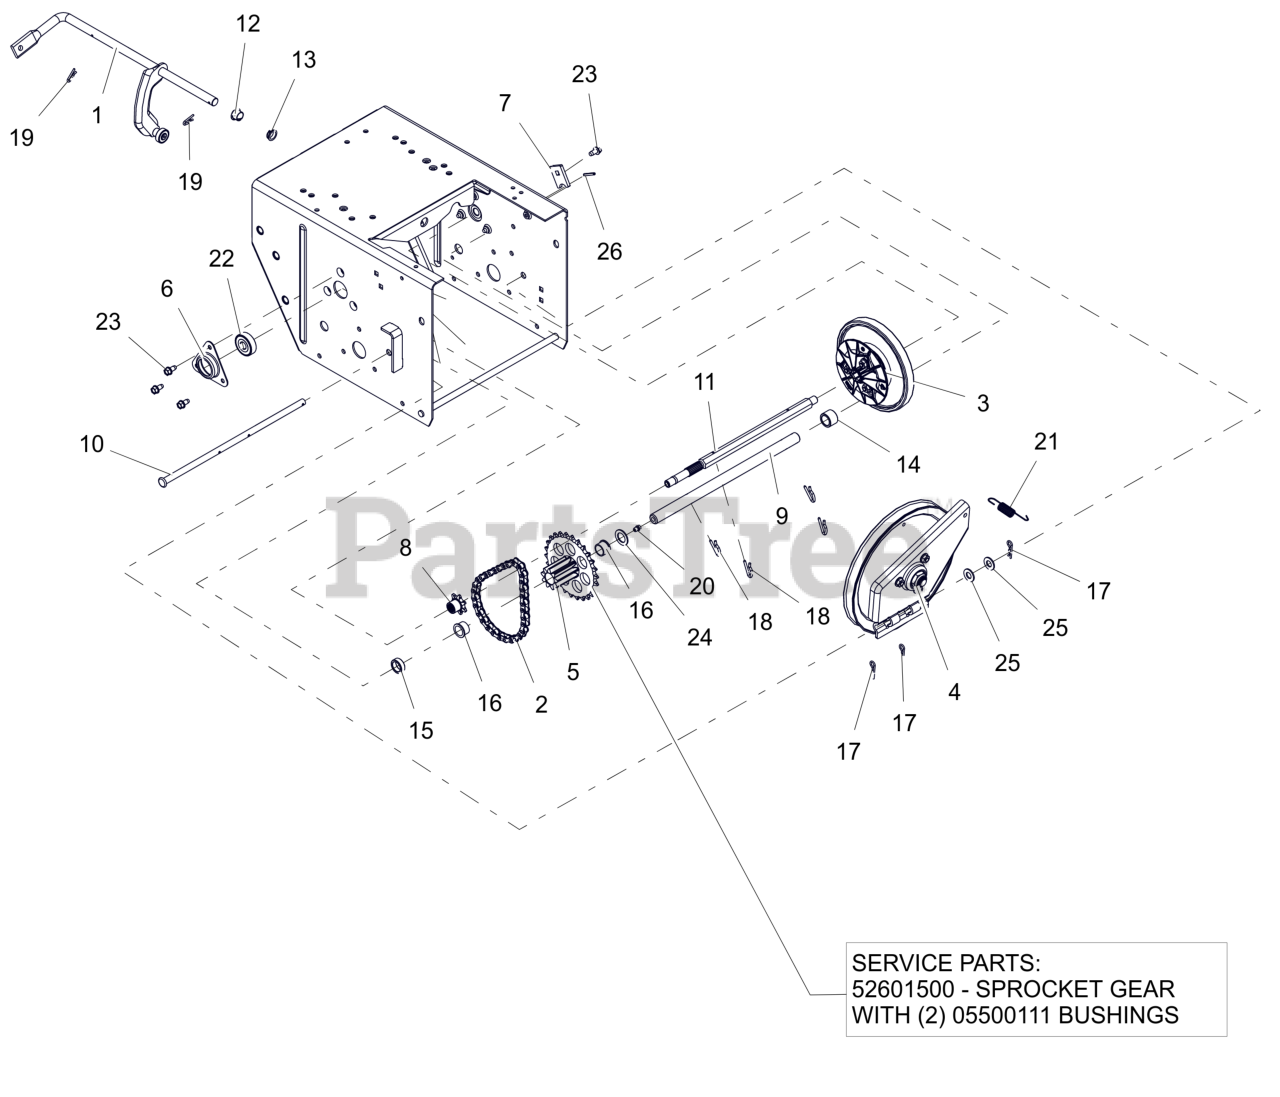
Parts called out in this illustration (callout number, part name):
1	ARM, SHIFT-PRO (ASSEMBLY)
2	CHAIN - #41, 32 PITCHES
3	DISC, FRICTION DRIVE-ASSEMBLY
4	PLATE, SWING ASSEMBLY-DEEP
5	PINION & SPROCKET
6	FLANGE, BEARING
7	TAB, ANTI ROTATION
8	SPROCKET, PINION 7T W/SPLINE
9	SHAFT, PINION - HARDENED
10	PIN, PIVOT
11	SHAFT, HEX - HEAT TREATED
12	BUSHING, POLYLINER-.50 SPLIT
13	BUSHING, POLYLINER-.50 SNAPIN
14	SPACER, .635X.880X.611
15	BSHG-SLV, .635X.880X.305
16	BSHG-FLG .625X.750X.500X.875
17	PIN, HAIR #213 .08X1.19 ZCC
18	PIN, SPRING CLIP
19	CLIP, SPRING
20	ZERK,FITTING .25X.125 DRIVE IN
21	SG-TENS .048X.50X2.8
22	BRG-BALL .437X1.375X.437
23	SCR-TAP .25-20X.50 HWH ZCC
24	WSHR, FLT .630X1.005X.062 ZCC
25	WSHR,FLT .406X.812X.065 ZCC
26	PIN-ROLL .125X1.00
